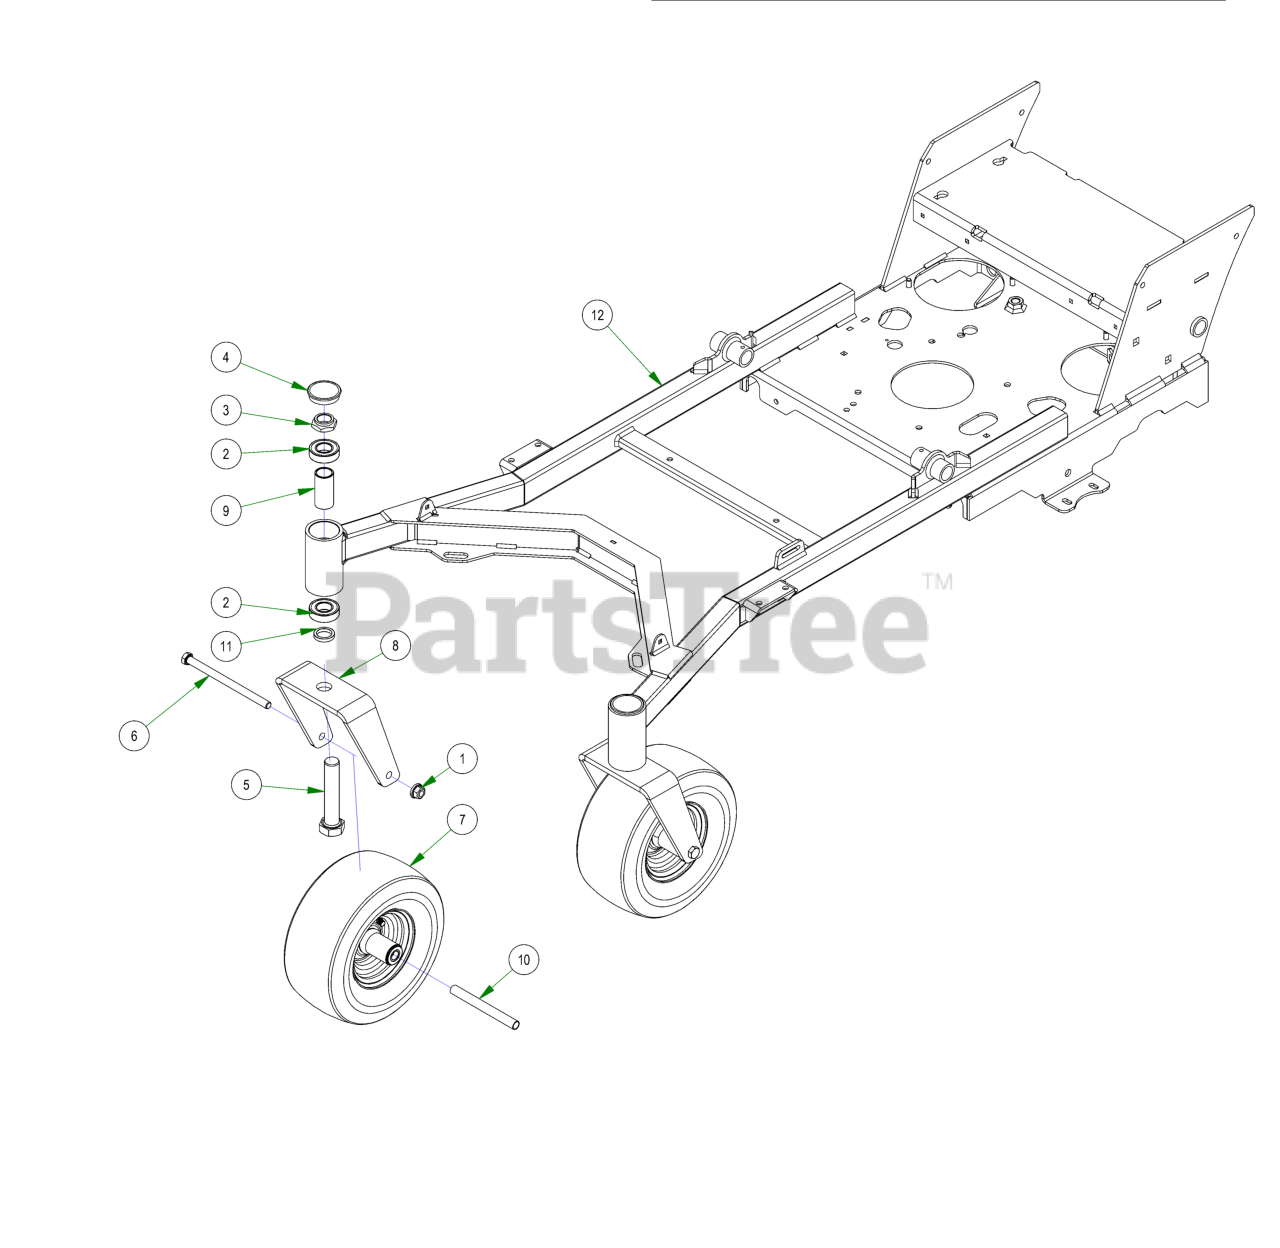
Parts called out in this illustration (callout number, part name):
1	1/2-13 NYLON INSERT FLANGE LOCKNUT ZINC
2	1641 BEARING W/2 CONTACT RUBBER SEALS
3	1"-14 NYLON INSERT JAM LOCKNUT ZINC
4	2017 Bearing Cover
5	1"-14 X 5 HEX CAP SCREW (GR.8) ZINC YELLOW
6	1/2-13 X 7-1/2 HEX CAP SCREW (GR.5) ZINC
7	11x6.00-5 Front Assembly - Black Wheel
8	2017 MZ Front fork
9	2016 Front Bearing Spacer
10	Front Wheel Spanner
11	1.02 ID X 1.38 OD X .250 THK SPACER ZINC
12	2023 Walk Frame
